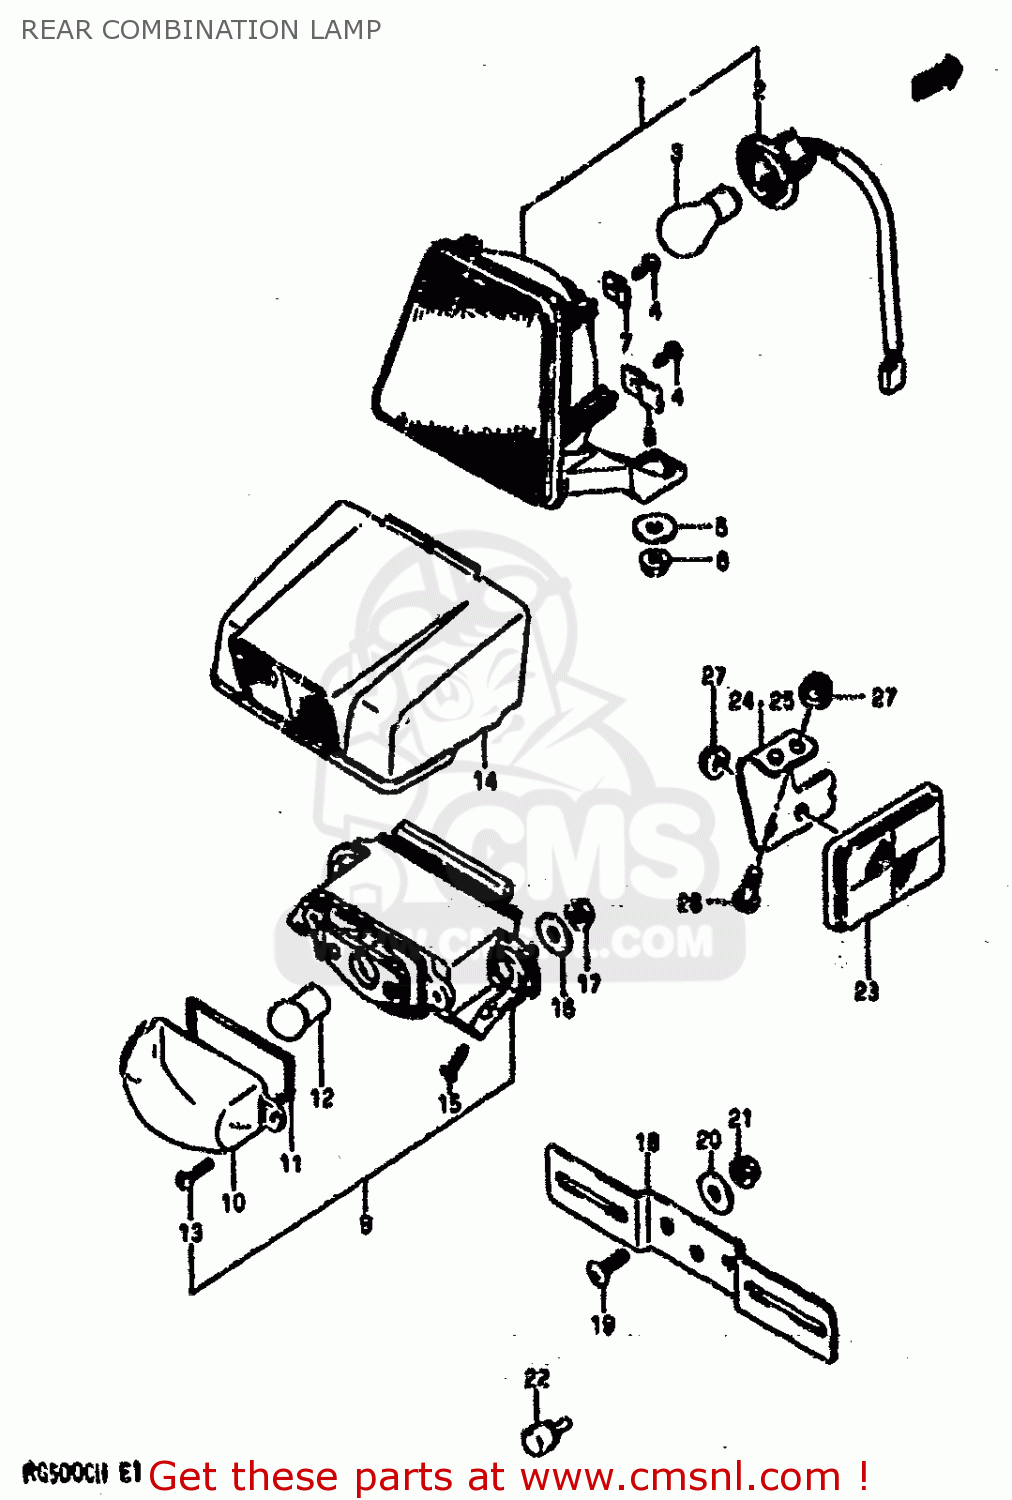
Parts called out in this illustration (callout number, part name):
1	LAMP ASSY, REAR COMBINATION
2	SOCKET
3	BULB,12V,12W
4	SCREW
5	WASHER
6	NUT
7	PLATE,UPPER
8	PLATE,LOWER
9	LAMP ASSY, LICENSE PLATE
10	LENS,LICENSE LAMP
11	GASKET,LICESE LAMP (NAS)
12	BULB
13	SCREW
14	COVER,LICENSE LAMP
15	SCREW
16	WASHER
17	NUT
18	PLATE,RR LICENSE
19	SCREW
20	WASHER
21	NUT
22	CUSHION
23	REFLEX REFLECTOR, REAR SIDE
24	BRACKET,RH
25	BRACKET,LH
26	SCREW 5X10
27	NUT ,5MM
